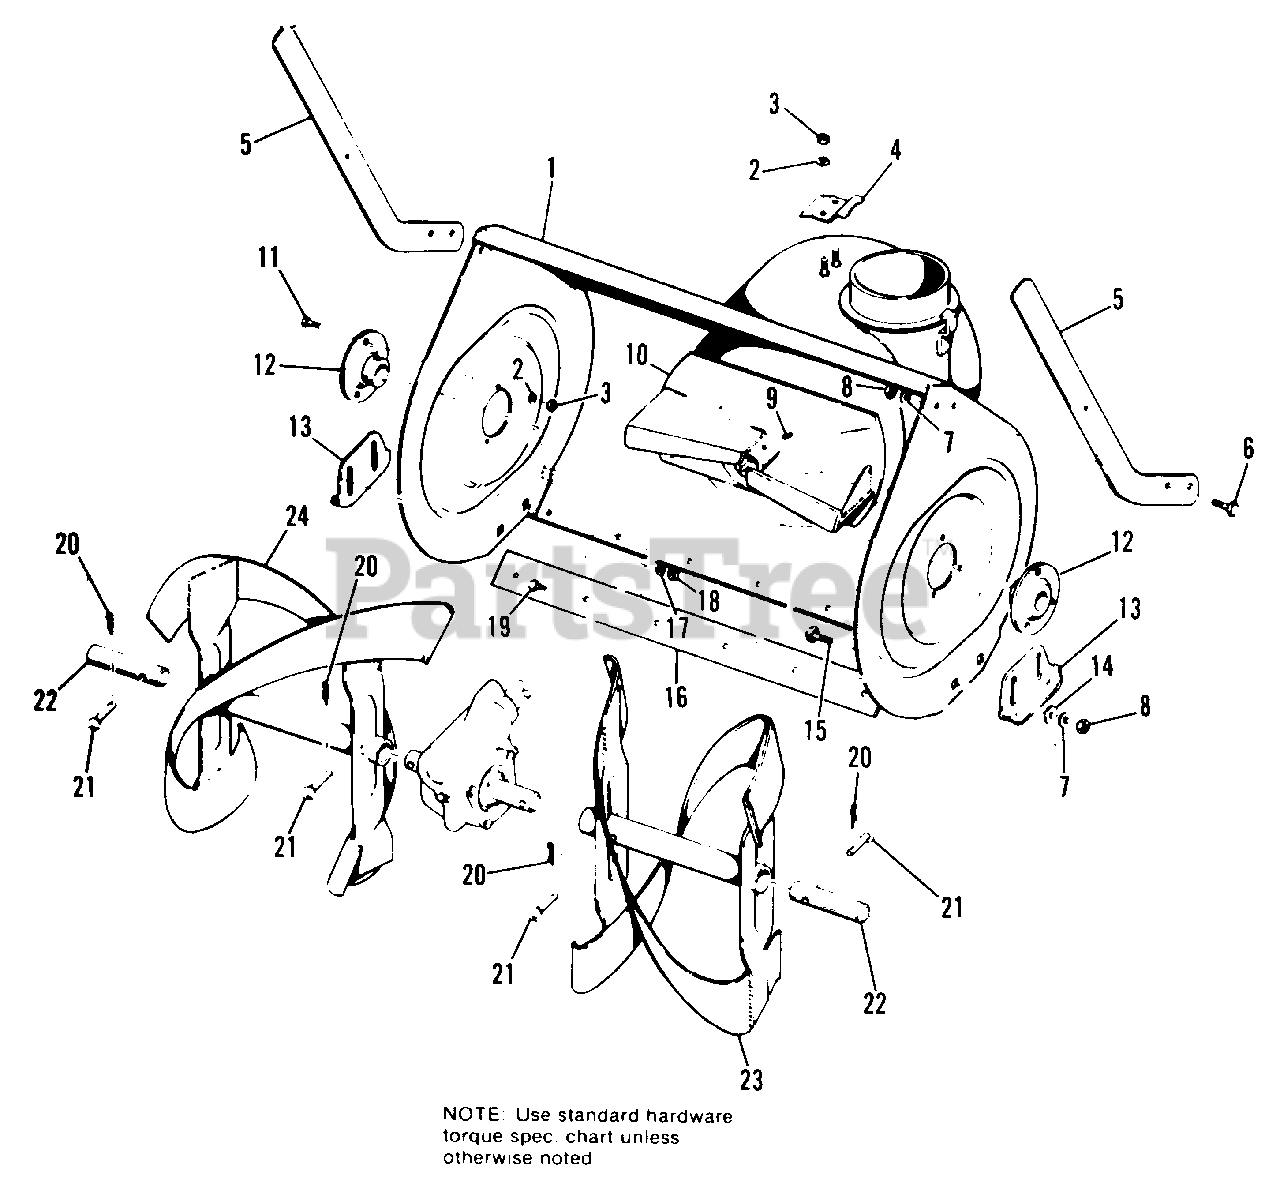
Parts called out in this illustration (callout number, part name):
1	BODY ASSY.
2	LOCKWASHER, 5/16
3	NUT, Hex, Full, 5/16-18
4	CLIP, Hold Down
5	CUTTER, Drift
6	CAPSCREW, Hex Hd., 3/8-16 x 3/4
7	LOCKWASHER, 3/8
8	NUT, Hex, Full, 3/8-16
9	SETSCREW, 5/16-18 x 3/8
10	IMPELLER ASSY.
11	CAPSCREW, Hex Hd., 5/16-18 x 3/46
12	BEARING, Ball
14	WASHER, Plain, 3/8
15	BOLT, Carriage, 3/8-16 x 3/4
16	BLADE, Scraper
17	LOCKWASHER, 1/4
18	NUT, Hex, Full, 1/4-20
19	CAPSCREW, Hex Hd., 1/4-20 x 5/8
20	PIN, Cotter, 1/8 x 1
21	PIN
22	SHAFT, Auger
23	AUGER ASSY. L.H.
24	AUGER ASSY. R.H.
